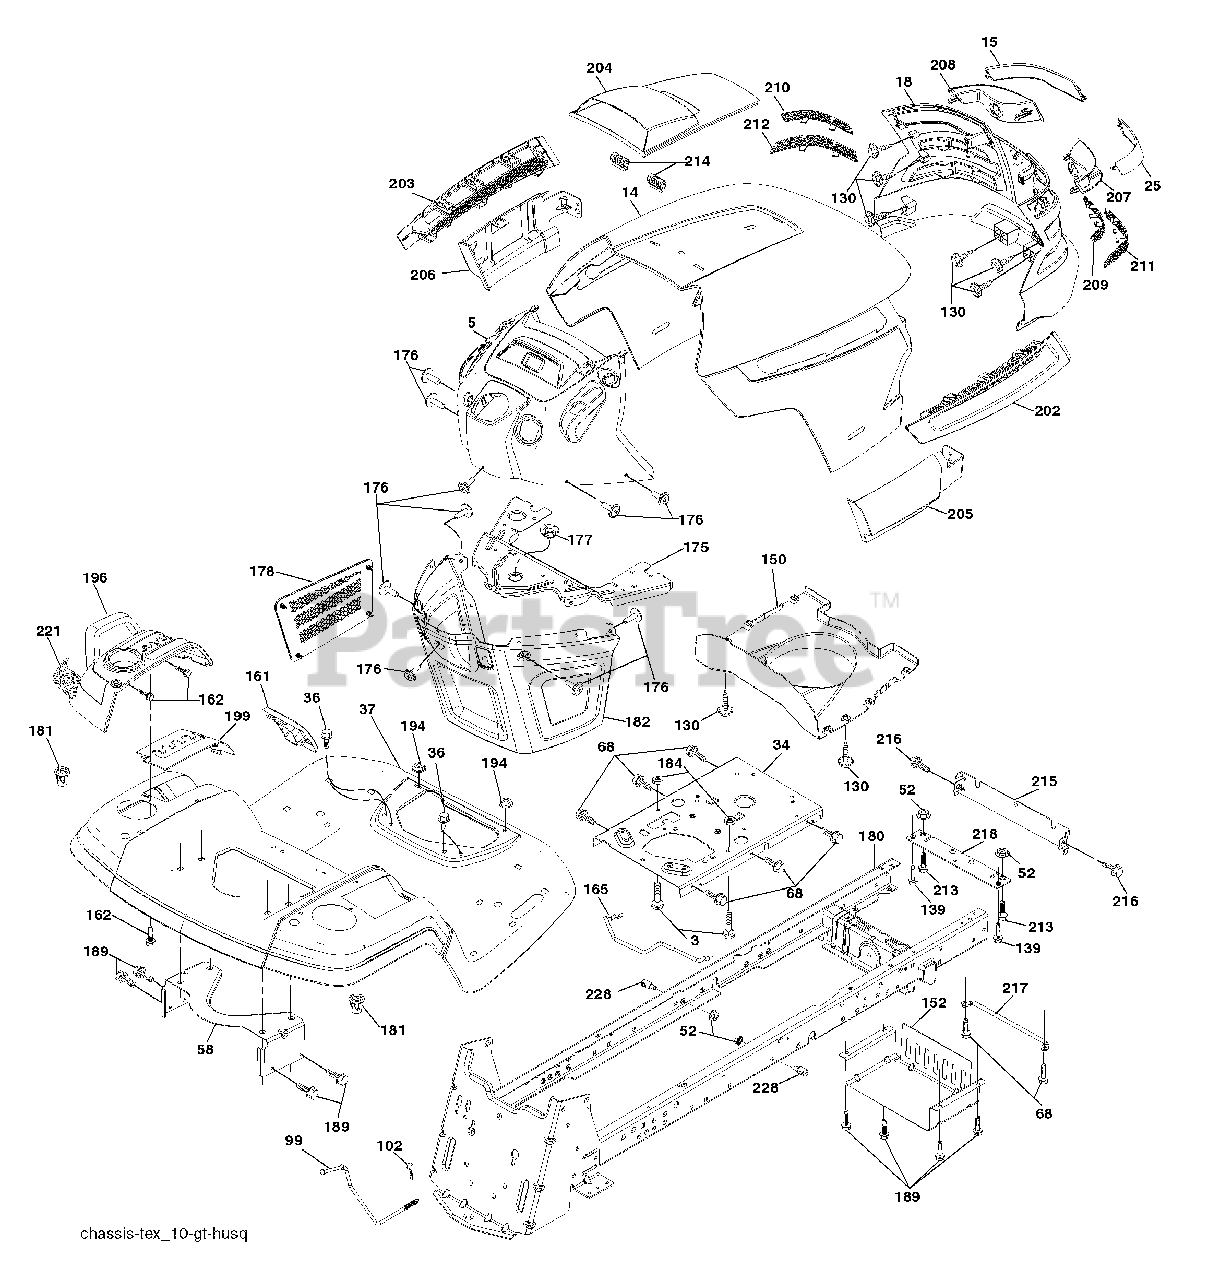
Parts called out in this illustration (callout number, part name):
5	Dash
14	Hood
18	Grille
34	Plate Engine
36	Screw 5/16-18 x 3/4
37	Fender
52	Nut Crown Lock 5/16-18
58	Bracket Fender
68	Screw 5/16-18 x 1/2
99	Rod Bypass Asm.
102	Retainer Spring
130	Screw 10 x 3/4 Single Lead Hex
139	Bolt Shoulder 5/16-18
150	Duct Heat Hood
152	Shield Browning/Debris
161	Console Fuel Window
162	Screw Hex Wsh Hi-Lo 1/4 x 1/2
165	Bracket Support Tank
175	Crossmember
176	Screw 10-24 x 5/8 RND Qdrx
177	Bushing Steering
178	Cargo Asm. Net
181	Bushing Mtg. Fender Crgo.
182	Dash Lower
183	Bolt Fin Hex 5/16-18 UNC x 1-1/4
184	Spacer Fender
189	Screw 5/16-18 x 3/4
194	Nut Lock Hex Flange 5/16-18
196	Console Asm. Deck Lift
199	Plate Deck Lift
202	Vent Side Hood RH
203	Vent Side Hood LH
204	Vent Asm Hood Top
205	Skirt Hood Side RH
206	Skirt Hood Side LH
209	Insert Hex Top RH
210	Insert Hex Top LH
211	Insert Hex Bottom RH
212	Insert Hex Bottom LH
213	Bolt Hex Hd 5/16-18 unc x 3/4
214	Clip Retainer
215	Cover Chassis Front
216	Screw 5/16-18 x 1/2
217	Rod Pivot
221	Reflector LH
228	Stud Fastener
